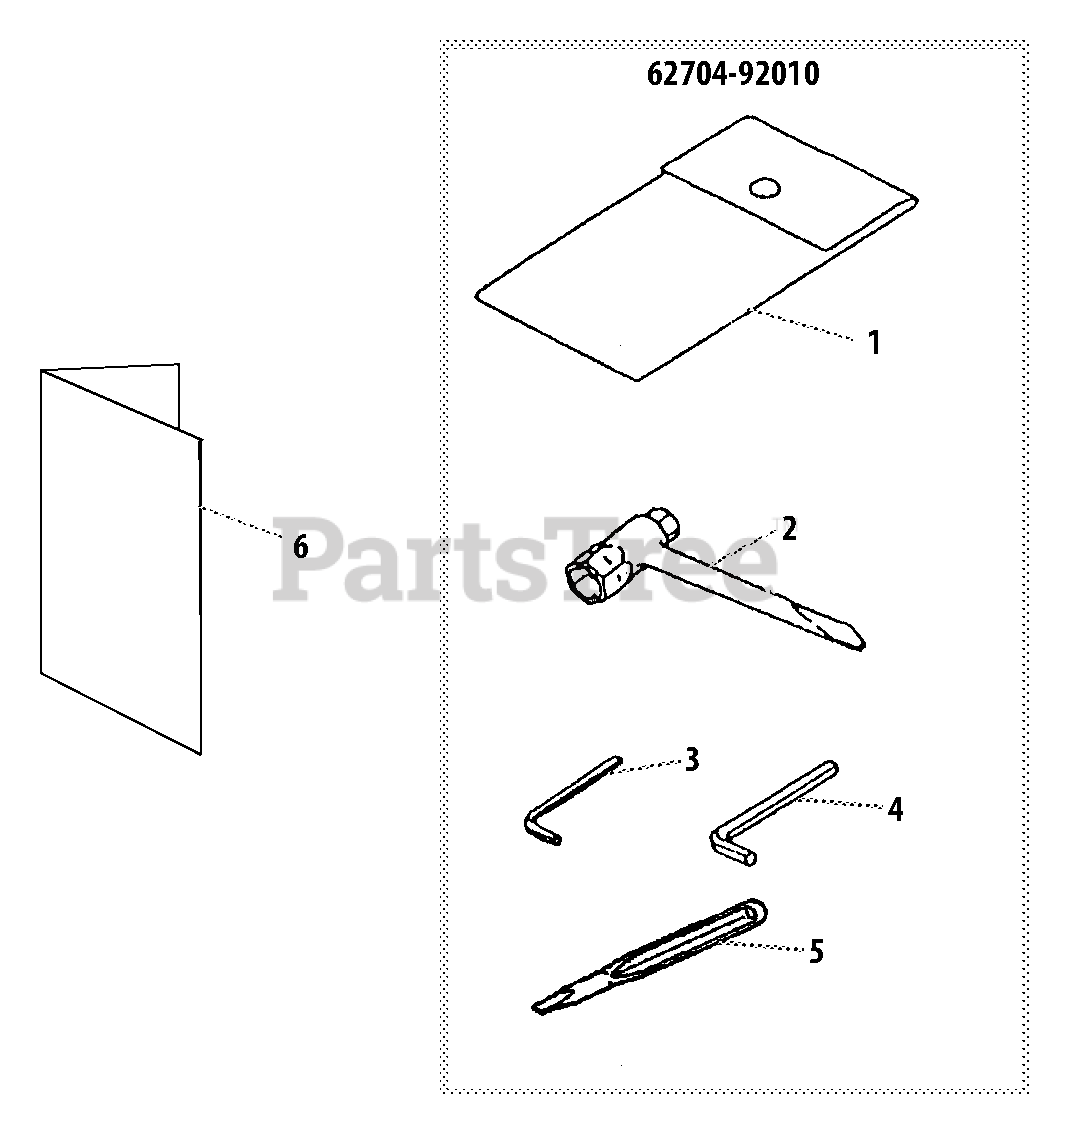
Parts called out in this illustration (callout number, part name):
1	BAG, TOOL
2	T-WRENCH - 13X19mm
3	HEX KEY - 3mm
4	HEX KEY - 4mm
5	SCREWDRIVER - PLASTIC
6	OWNERS MANUAL
62704-92010	TOOL KIT
